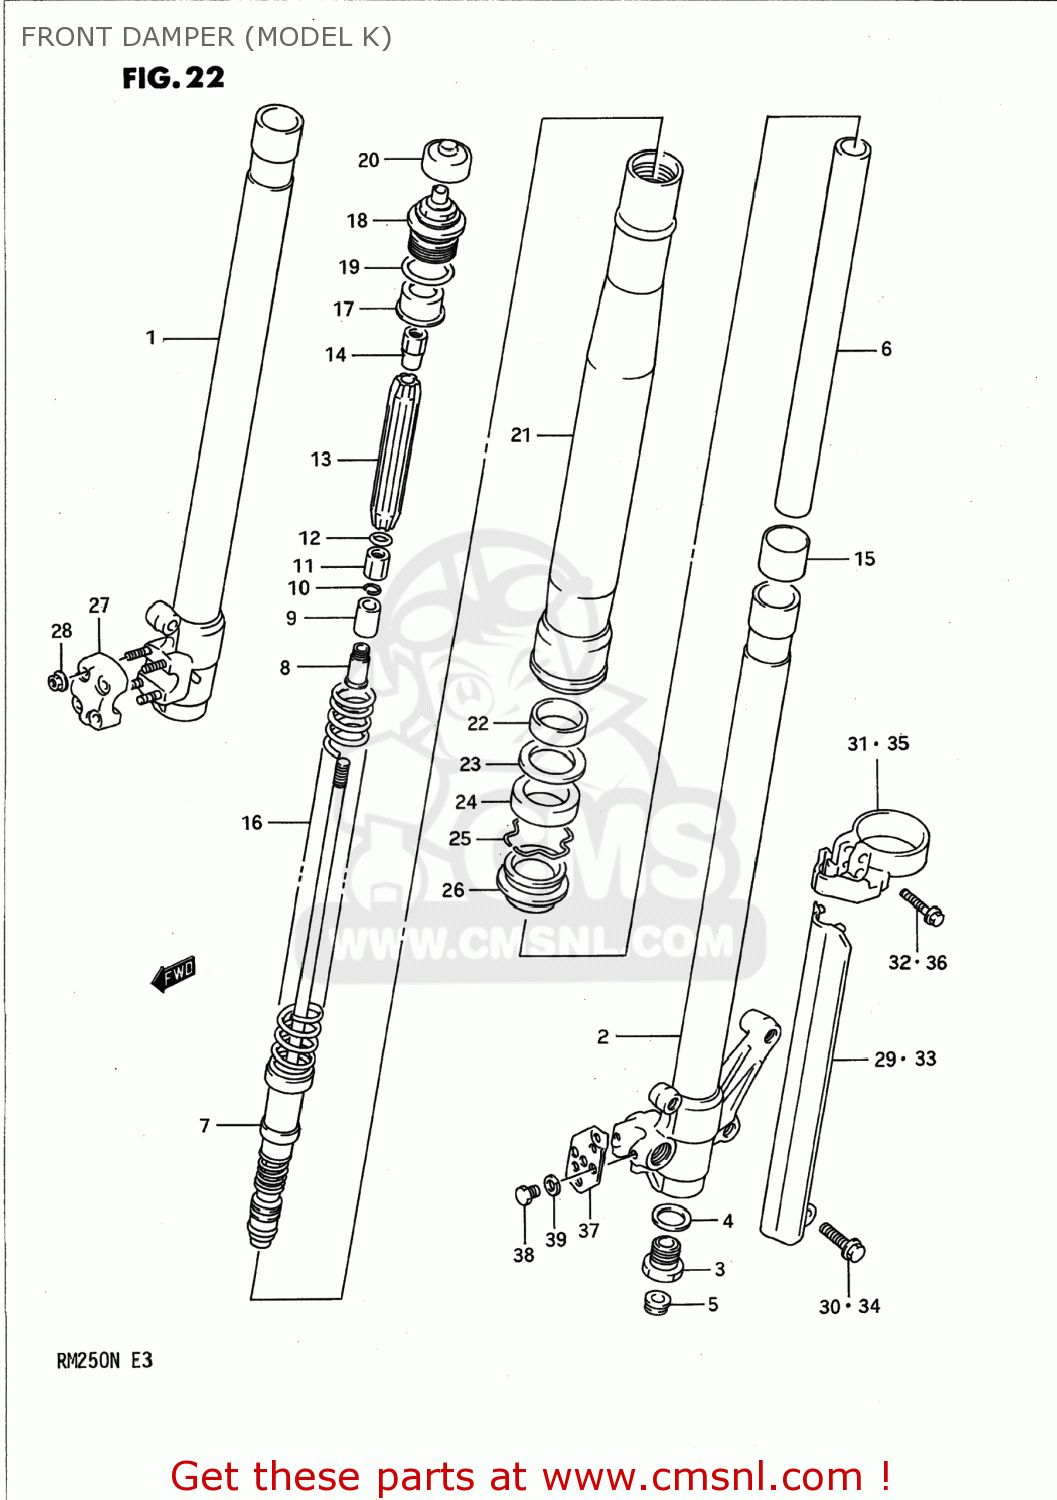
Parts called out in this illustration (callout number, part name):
1	TUBE,INNER,RIGHT
2	TUBE,INNER,LEFT
3	BASE,VALVE ASSEMBLY
4	GASKET (NAS)
5	CAP,RUBBER
6	CYLINDER
7	ROD ASSEMBLY,PISTON
8	HOLDER,PIECE
9	PIECE,OIL LOCK
10	RING,SNAP
11	NUT
12	O-RING
13	GUIDE,SPRING
14	NUT,PISTON ROD
15	PISTON
16	SPRING
17	GUIDE,SPRING
18	CAP
19	O RING
20	CAP
21	TUBE,OUTER
22	METAL,SLIDE
23	WASHER,FORK OIL SEAL
24	OIL SEAL,FRONT FORK
25	RING,OIL SEAL STOPPER
26	SEAL,DUST
27	HOLDER,AXLE
28	NUT
29	PROTECTOR,R
30	BOLT
31	HOLDER
32	BOLT, GUIDE
33	PROTECTOR,L
34	BOLT
35	GUIDE
36	BOLT, GUIDE
37	COVER,HOSE
38	BOLT 5X10
39	LOCK WASHER
